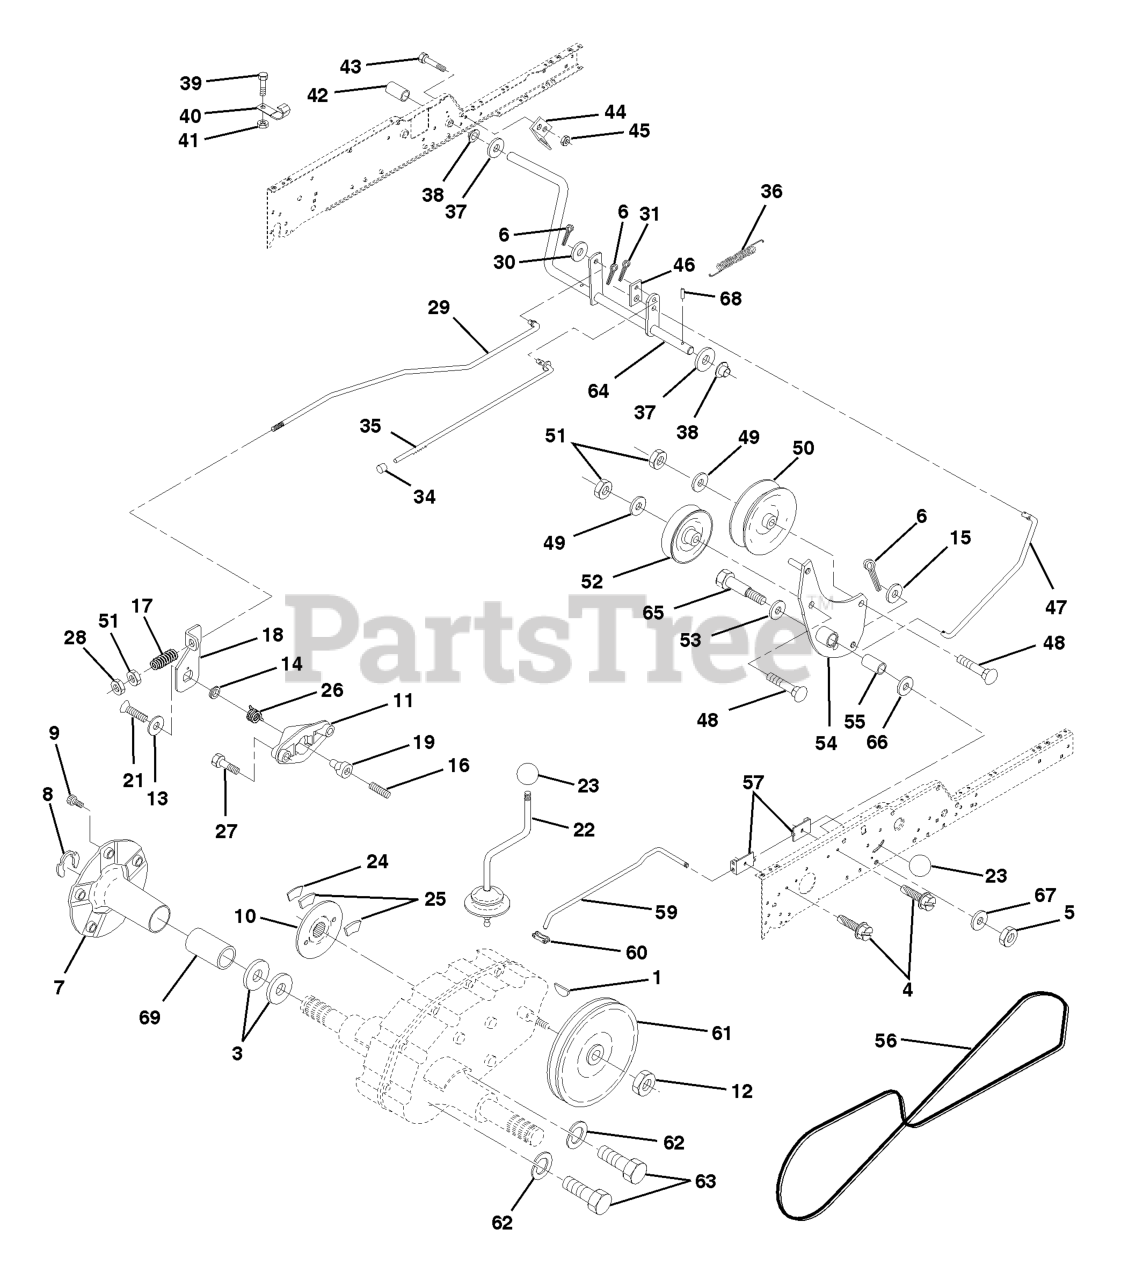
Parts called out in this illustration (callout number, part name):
1	KEY
4	Screw Thdrol 5/16-18 x 1/2 TYT
6	COTTER PIN
7	BUSHING ASS'Y AND WHEEL HUB
9	HUB BOLT
10	BRAKE DISC
11	YOKE-BRAKE DISC
15	WASHER
17	SPRING,ROD BRAKE
18	BRAKE LEVER
19	BRAKE DISC CAM
21	Screw Flat Head 1/4-28 x 3/4
22	GEAR SHFT LVR T
24	BRAKE PUCK SUPPORT
25	BRAKE PUCK TOP
26	RETURN SPRING
27	SCREW
28	NUT
29	ROD BRAKE ZINC GT
30	WASHER
31	COTTER PIN
34	PLUNGER CAP
35	PARKING BRAKE ROD
36	SPRING EXTENSION
39	Screw Fin #10-24 x 1
40	ACT-SWITCH T
41	LOCKNUT
42	COVER, PEDAL (1 2)
43	BOLT.HEX.1/4.X.3/4.DICHROMATE
44	BRKT SWITCH GT
45	LOCKNUT.NYLOC.1/4-20
46	RETAINER SPRING
47	CLUTCH ROD
49	Washer 13/32 x 7/8 x 13 Ga
50	FLAT IDLER PULLEY
51	NUT
52	PULLEY.IDLER.V.
54	CLUTCH ARM ASSY
55	BEARING LT (2 2)
56	V-BELT GROUND DRIVE
57	BRACKET SHIFT ROD
59	ROD SHIFT HI LO
60	CONNECTING LINK
61	TRANSAXLE PULLEY
62	LOCKWASHER
63	BOLT
64	PEDAL SHAFT
66	WASHER.BLADE
67	WASHER
68	ROLL PIN STD
69	COVER.HUB.BLACK
